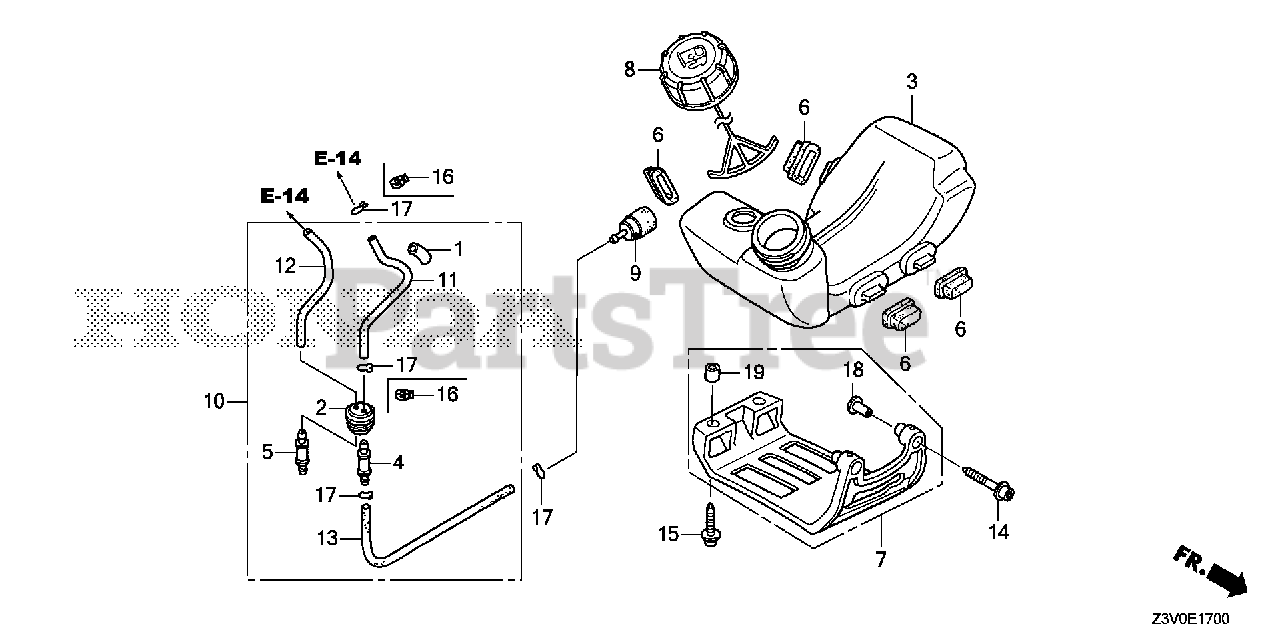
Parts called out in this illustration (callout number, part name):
1	PROTECTOR, TUBE
2	GROMMET, FUEL TUBE
3	TANK, FUEL
4	JOINT, FUEL TANK
6	RUBBER, TANK MOUNTING
8	CAP ASSY., FUEL TANK
9	FILTER, FUEL
10	GROMMET ASSY., FUEL TANK
11	TUBE, FUEL (FKM)
12	TUBE, FUEL RETURN
13	TUBE A, FUEL
16	CLAMP, TUBE
17	CLIP, TUBE (B1 5)
